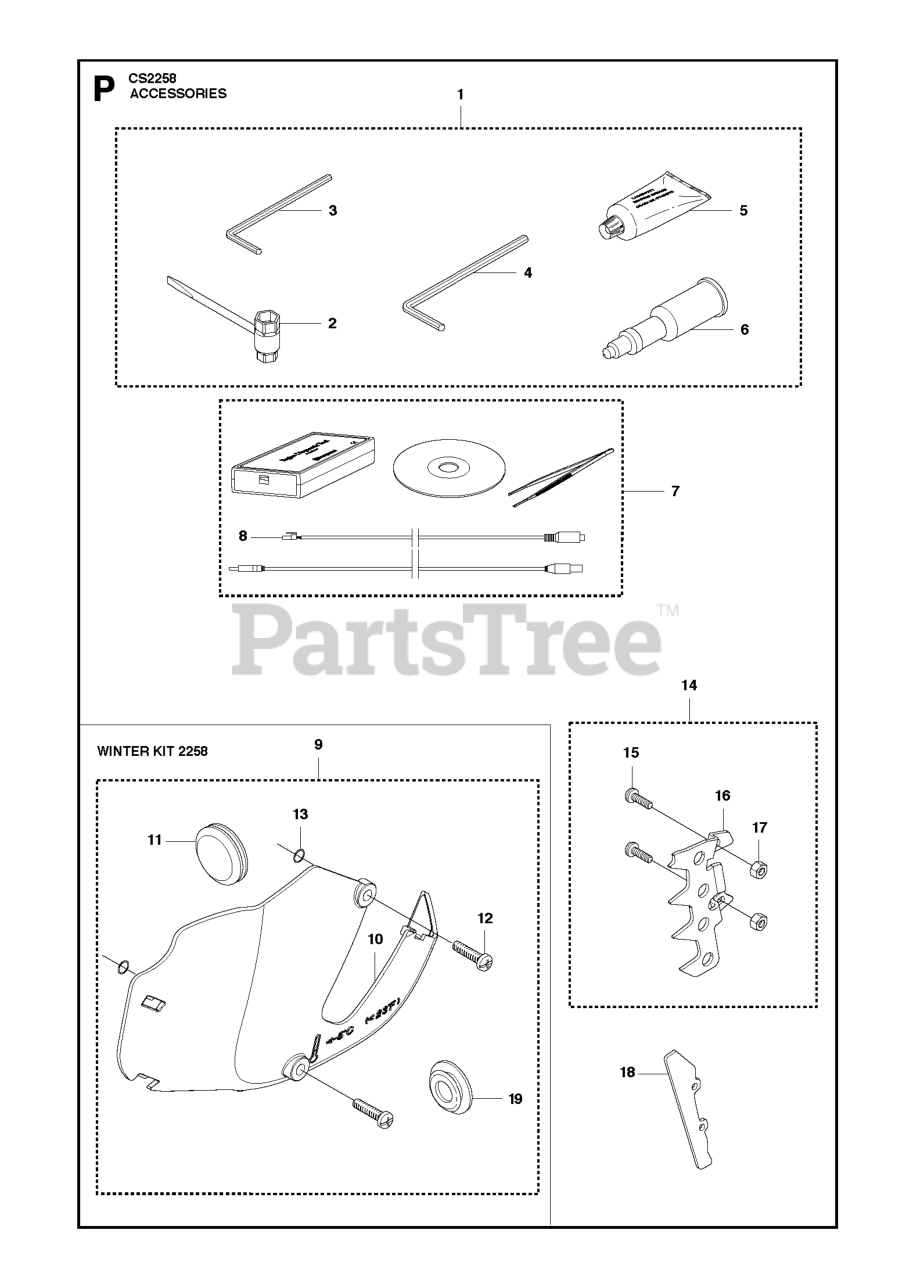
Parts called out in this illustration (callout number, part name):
2	COMBINATION WRENCH
3	L-SPANNER
4	L-SPANNER
5	GREASE
6	Grease Gun
7	SERVICE TOOLS
8	CABLE ASSY
9	WINTER KIT
10	WINTER COVER JONSERED
11	PLUG
12	SCREW
13	O-RING
14	SPIKE OUTER
15	SCREW
16	SPIKE OUTER
17	NUT
19	WINTER PLUG
